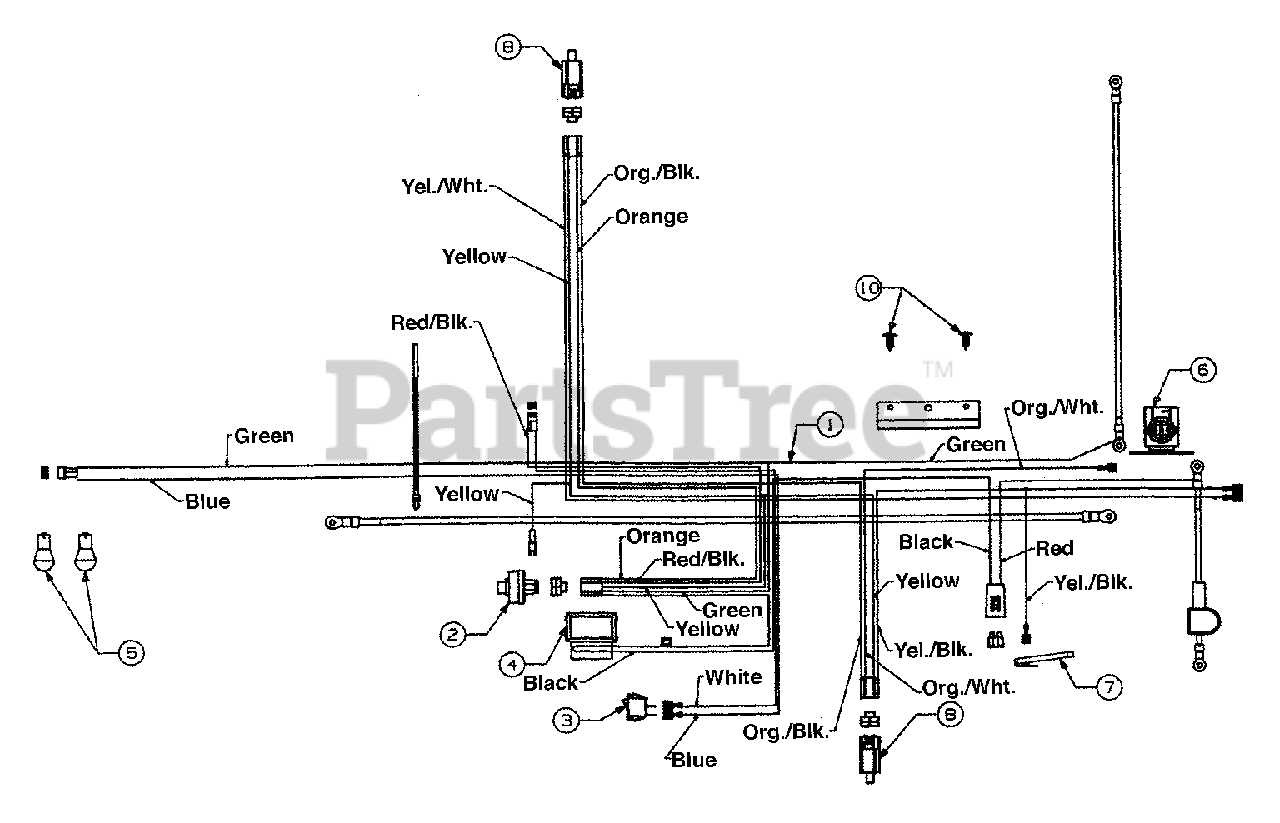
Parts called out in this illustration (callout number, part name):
1	Wire Harness w/Lt./Amp./Sw.
1	Wire Harness w/o Lt./Amp./Sw.
2	Ignition Switch - 5 Pin
2	Ignition Switch - 6 Pin
3	Light Switch
4	Ammeter (Optional)
5	Bulb (Headlight)
6	Solenoid
7	Safety Switch (Reverse)
8	Safety Switch
